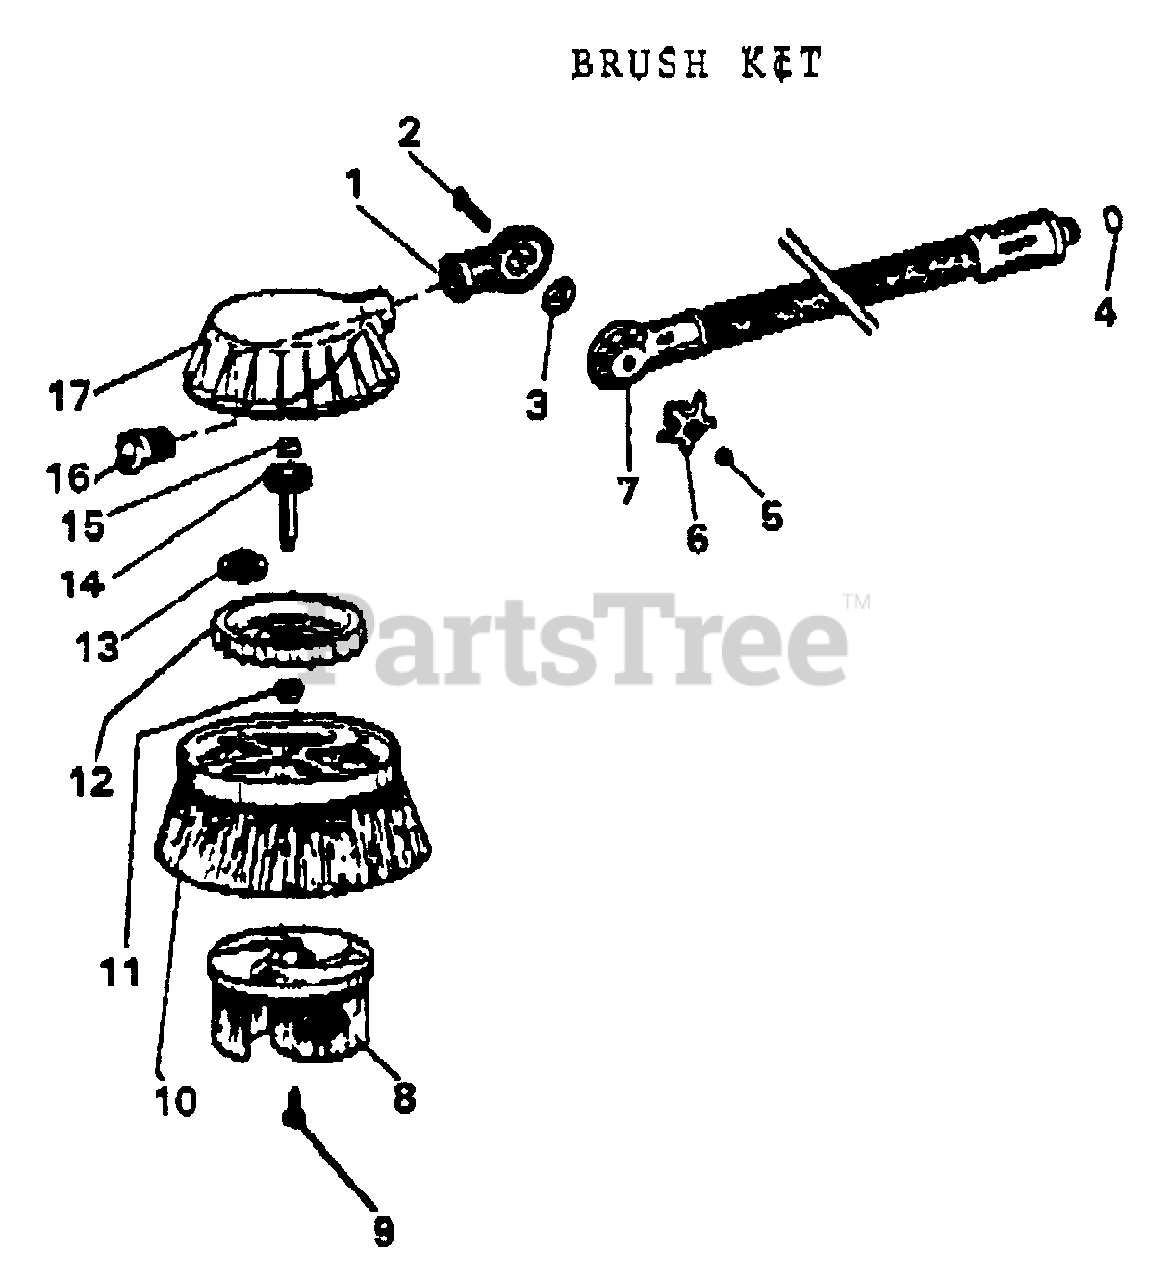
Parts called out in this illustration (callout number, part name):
1	CONNECTOR, ADJUSTABLE
2	SCREW - 6X40
3	GASKET, CONNECTOR
4	O-RING - .359 X .103
5	NUT - 6
6	KNOB, REGULATING
7	HAND GRIP, BRUSH
8	BRUSH, ROTATING
9	SCREW - 6X13
10	BRUSH, FIXED
11	BUSHING
12	TURBINE
13	GEAR
14	GEAR - SHAFT
15	BUSHING
16	NOZZLE, 3.85
17	COVER
